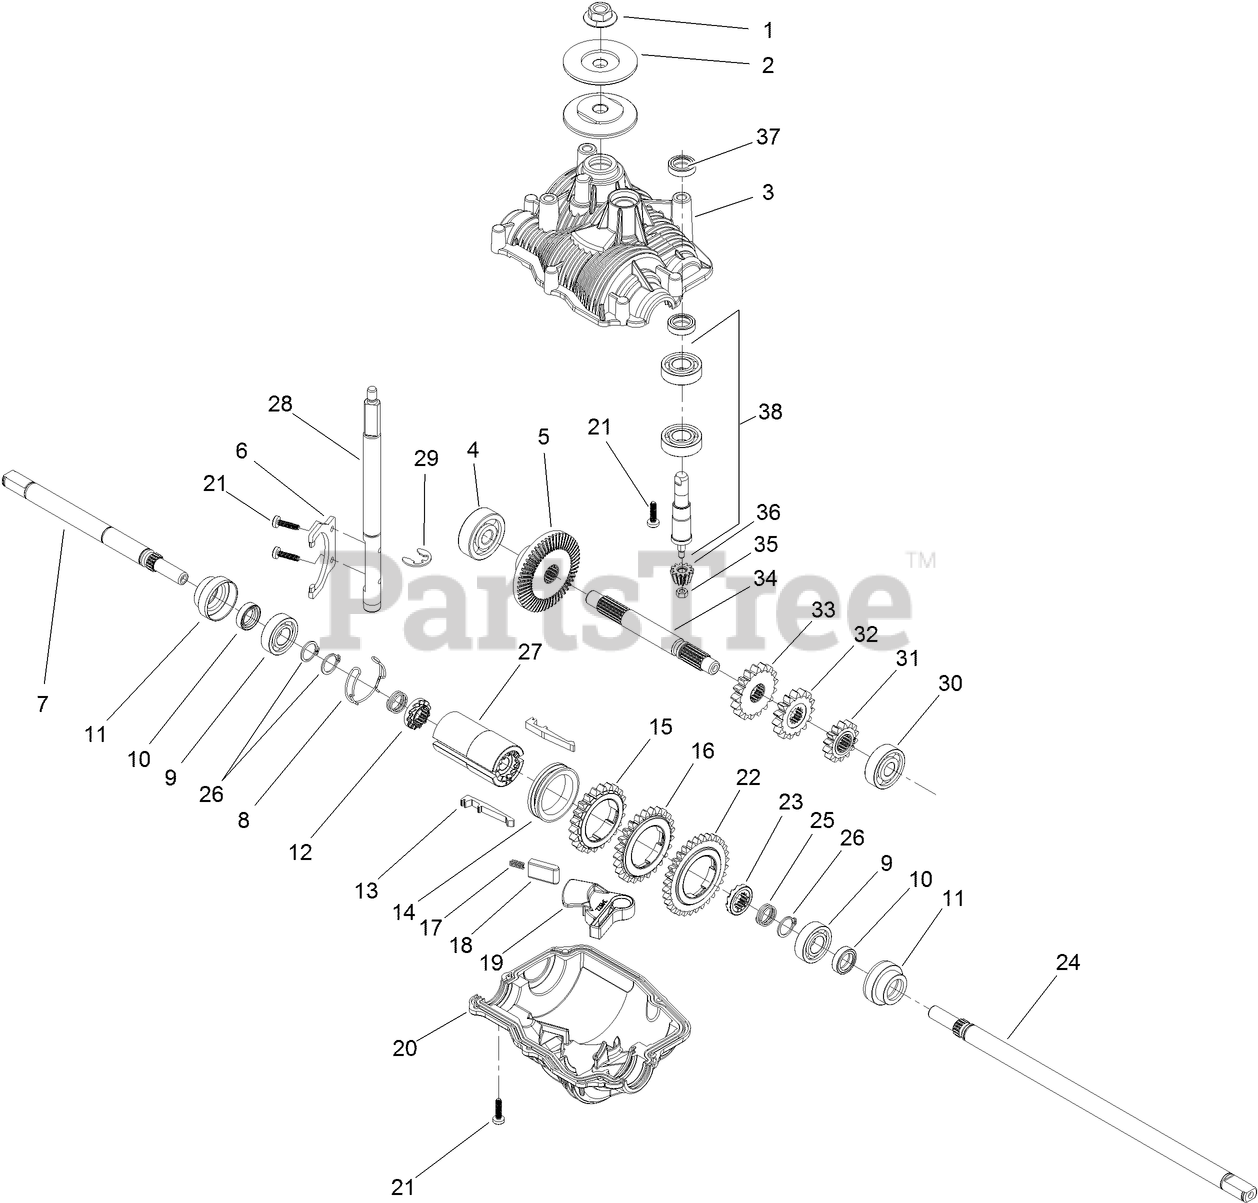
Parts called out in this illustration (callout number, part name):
1	NUT-FLANGE
2	FLANGE-PULLEY
3	CASE-UPPER, TRANSMISSION
4	BEARING-BALL
5	GEAR-BEVEL, 53 TOOTH
6	FORK-SHIFT
7	SHAFT-OUTPUT, SHORT
8	SPRING-RETAINING
9	BEARING-BALL
11	BUSHING-SHAFT, OUTPUT
12	CLUTCH-DOG
13	KEY-SHIFT
14	RING-SHIFT
15	GEAR-OUTPUT, 22 TOOTH
16	GEAR-OUTPUT, 25 TOOTH
17	SPRING-INDEXING, SHIFTER
18	PIN-INDEXING, SHIFTER
19	LEVER-INDEXING, SHIFTER
20	CASE-LOWER, TRANSMISSION
22	GEAR-OUTPUT, 32 TOOTH
23	CLUTCH-DOG, RH
24	SHAFT-OUTPUT, LONG
25	SPRING-COMPRESSION, CLUTCH
26	RING-RETAINING
27	HUB-GEAR, OUTPUT
28	SHAFT-SHIFT
29	RING-RETAINING
30	BEARING-BALL
31	GEAR-INTERMEDIATE, 14 TOOTH
32	GEAR-INTERMEDIATE, 15 TOOTH
33	GEAR-INTERMEDIATE, 17 TOOTH
34	SHAFT-INTERMEDIATE
35	NUT-SHAFT, INPUT
36	GEAR-BEVEL, 12 TOOTH
38	SHAFT-INPUT
